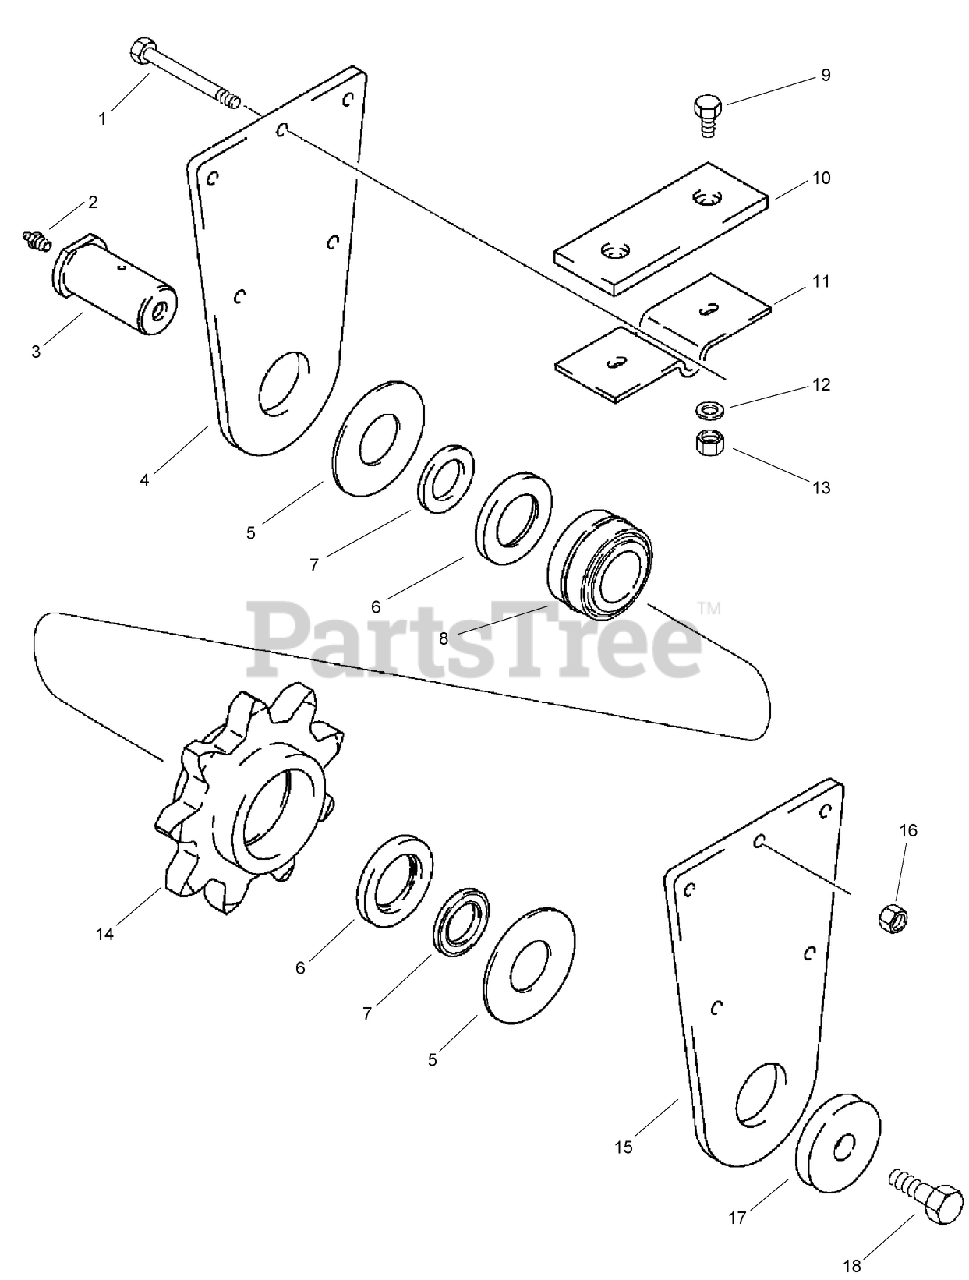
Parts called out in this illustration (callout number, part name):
1	BOLT-hex, 1/2 NC x 4-1/2 inch
2	FITTING-LUBE, STRAIGHT
3	PIN-sprocket
4	PLATE-idler sprocket mounting, left-hand
5	WASHER-BOOM, END (ROLLER)
6	SEAL-ROLLER
7	SPACER-bearing
8	BEARING KIT
9	SCREW-HH
10	PAD-wear, trencher boom
11	PLATE-mounting, wear pad
12	WASHER-FLAT
13	NUT-HEX
14	SPROCKET-boom idler
15	PLATE-idler sprocket mounting, right-hand
16	NUT-HEX
